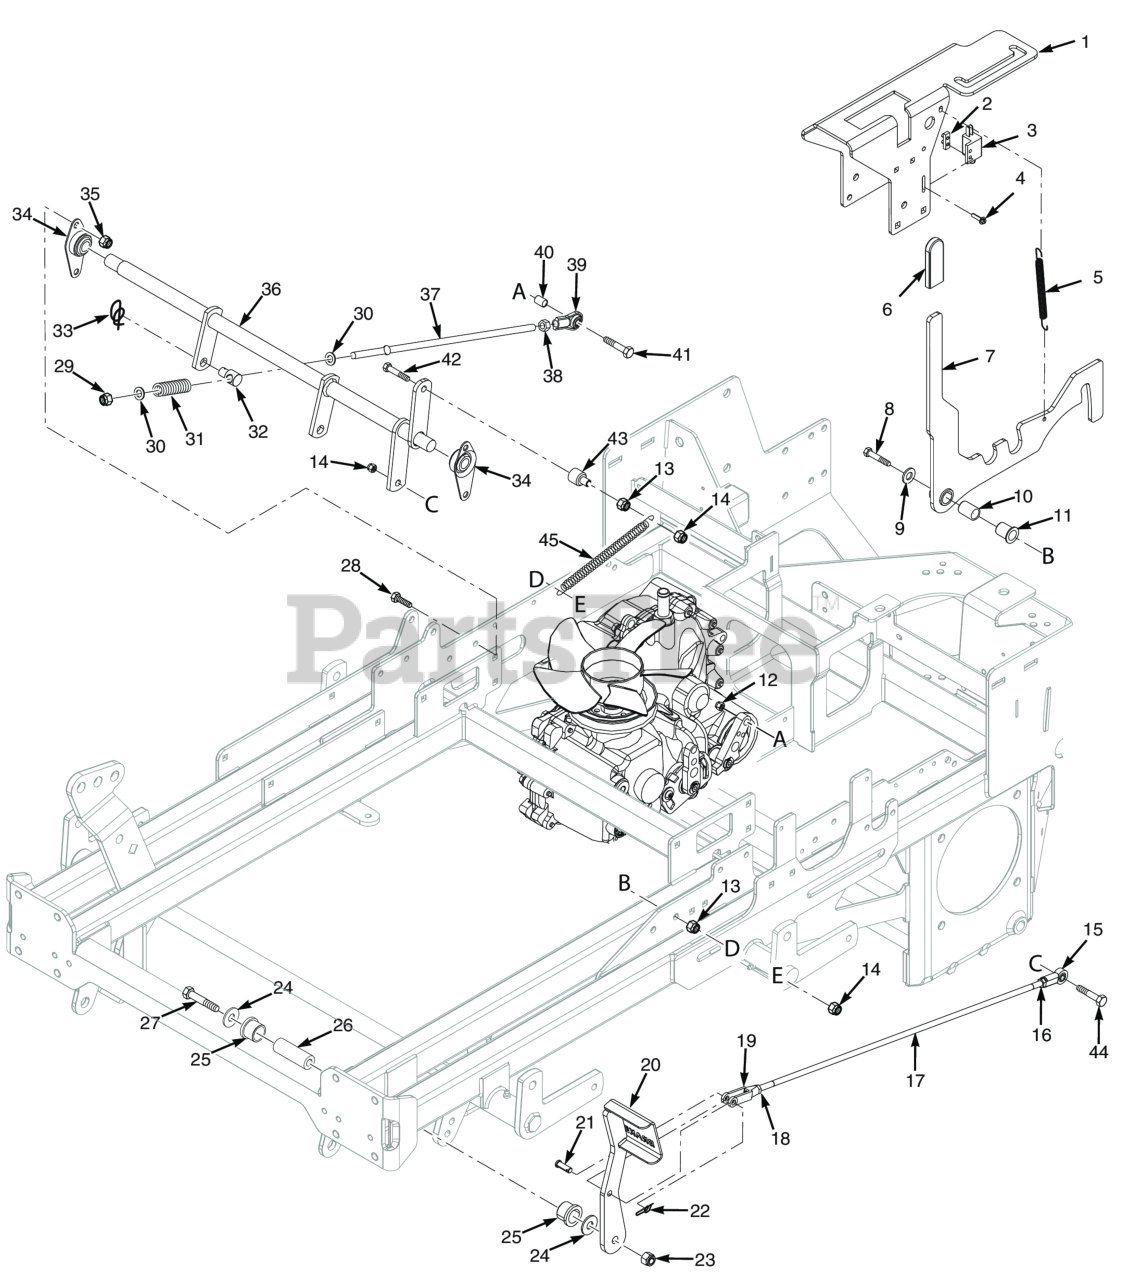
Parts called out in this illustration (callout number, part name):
1	Control Weldment w/ Decal
2	Plate, Threaded
3	Switch, N/C
4	Screw, Hex-Slotted Washer Head #10 32 x 3/4"
5	Spring, Deck Latch
6	Grip, Brake Handle
7	Brake Lever w/ Grip
8	Capscrew, Hex Head 3/8-16 x 2-1/2"
9	Flatwasher, 3/8 (.391 x .938 x .105 HD) Grade 8
10	Pivot, Brake Lever
11	Bearing, .625 ID Plastic
12	Nut, Center Lock, 5/16-18(32)
13	Bolt, Hex Head 3/8-16 x 1" Ser. Flg.
14	HEX NUT, ELASTIC STOP LOCK, 3/8-16
15	Rod End, 3/8-24 LH Thread Female
16	Nut, 3/8-24 UNF-2B LH Thread
17	Brake Rod Assembly (INCL. 15,16,18,19)
18	Nut, 3/8-24 UNF R.H. Thread
19	Clevis, Traction Control
20	Brake Pedal
21	Pin, Clevis 3/8-16 x 1-1/16"
22	Pin, Rue Cotter 3/8" Diameter
23	HEX LOCKNUT, ELASTIC STOP, 1/2-13
24	Flat Washer, 1/2 (.562 x 1.375 x .109)
25	Bearing, Plastic
26	Sleeve, Brake Pivot
27	Bolt, Hex Head 1/2-13 x 4-1/4"
28	BOLT, SERRATED FLANGE HEX HEAD 5/16-18 X 3/4"
29	Nut, Elastic Stop 3/8-24
30	FW, .375-.376/.380 X .734 X .063
31	Spring
32	BUSHING, PIVOT SLIDE
33	Pin, Rue Cotter 1/2" Dia.
34	Bearing, Self Align
35	Nut, Flange Head Elastic Stop 5/16-18
36	Brake Linkage Weldment
37	Brake Linkage Assembly (INCL. 29,30,31,32,38,39)
38	HEX NUT, 3/8-24 R.H. THREAD
39	Rod End, 3/8-24
40	Spacer, Pump
41	Bolt, 5/16-18 x 2-1/2"
42	Capscrew, Hex Head 3/8-16 x 2.75"
43	Pivot, Idler - Short
44	BOLT, HEX HEAD, 3/8-16 X 1-1/4
45	SPRING, HOPPER DOOR
